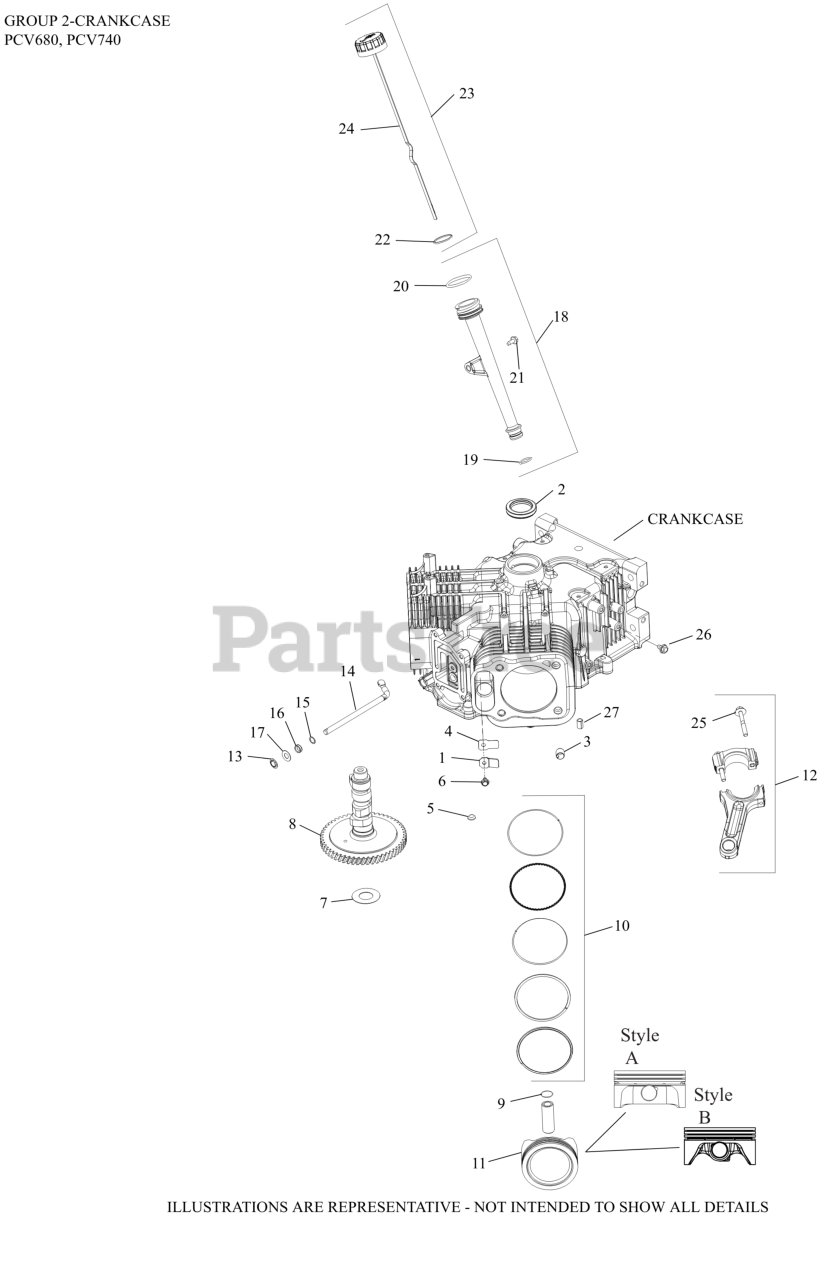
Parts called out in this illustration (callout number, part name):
1	RETAINER, BREATHER REED
2	SEAL, OIL (HELIX LIP)
3	PIN, LOCATING
4	REED, BREATHER-(#2440207S)
5	PLUG, CUP
6	SCREW, FLG THD FRM M5X.8X10
8	KIT, CAMSHAFT
9	RETAINER, PISTON PIN
10	RING DISC USE PISTON ASSY PER SPEC
10	RING SET(.08)STYLE A-1.5mm Tp RING THICK
10	RING SET(.25)STYLE A-1.5mm Tp RING THICK
10	RING SET(.50)STYLE A-1.5mm Tp-(#DSC)
10	RING SET(STD)STYLE B-1.2mm Tp RING THICK
10	RING SET(.08)STYLE B-1.2mm RING THICK
10	RING SET(.25)STYLE B-1.2mm Tp RING THICK
10	RING SET(.50)STYLE B-1.2mm Tp RING THICK
11	KIT,PSTN/RNG STYLE A(STD)(#2587406S)
11	KIT,PSTN/RNG STYLE A(.08)
11	KIT,PSTN/RNG STYLE A(.25)USE 2587411-S
11	KIT,PSTN/RNG STYLE A(.50)(#2587404S)
11	KIT,PSTN/RNG STYLE B(STD)
11	KIT,PSTN/RNG STYLE B(.08)
11	KIT,PSTN/RNG STYLE B(.25)
11	KIT,PSTN/RNG STYLE B(.50)
12	ROD, ASSEMBLY CONNECTING
13	RETAINER, RING
14	SHAFT, GOVERNOR CROSS
15	WASHER, FLAT 11/32"
16	SEAL, GOVERNOR CROSS SHAFT
17	WASHER, FLAT 9 MM
18	TUBE ASSEMBLY
19	O-RING, LOWER OIL FILL TUBE
20	O-RING, UPPER OIL FILL TUBE
21	SCREW, FLG THD FRM M5X0.8X13
22	O-RING, DIPSTICK
23	KIT, OIL FILL CAP (YELLOW)
24	DIPSTICK, ASSY
25	KIT, ROD BOLTS-(#25086677S)
